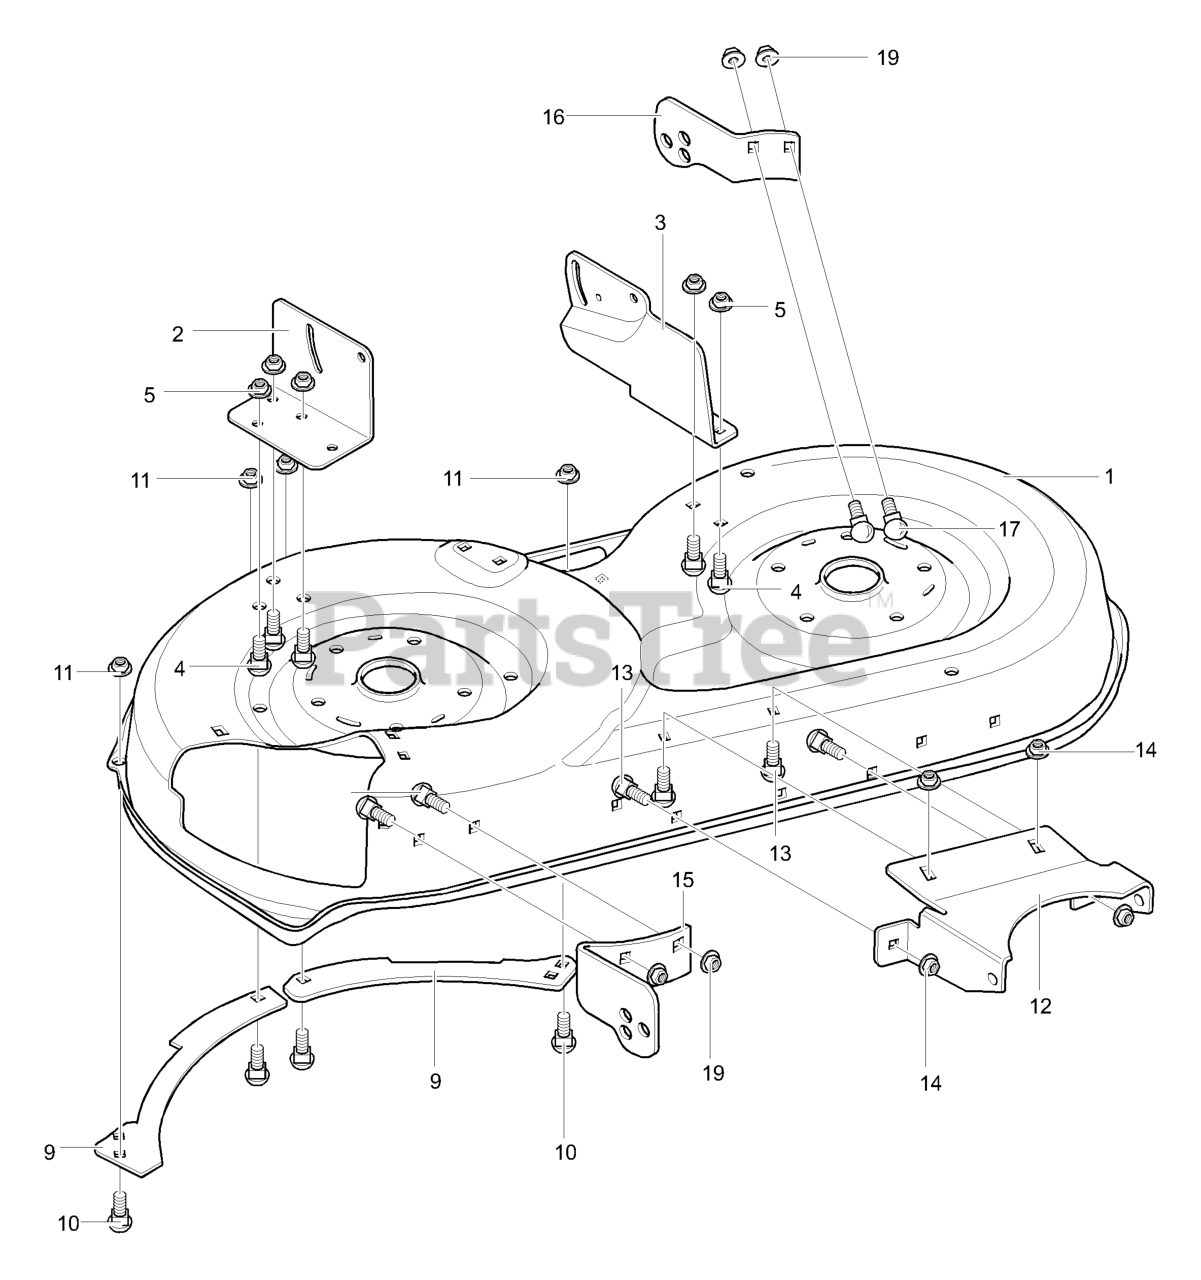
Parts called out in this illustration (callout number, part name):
1	42" Blade Housing
2	Bracket, Deck RH
3	Bracket, Deck LH
4	Bolt, .31-18x0.62
5	Nut, .32-18 Flangelock
9	Plate, Rear Toeguard
10	Bolt, .31-18x0.62
11	Nut, .32-18 Flng Ctrlk
12	Bracket, Front Deck
13	Bolt, .31-18x0.62
14	Nut, .31-18 Flangelock
15	Bracket, 42" Deck RH
16	Bracket, 42" Deck LH
17	Bolt, .31-18x0.62
19	Nut, .32-18 Flng Ctrlk
